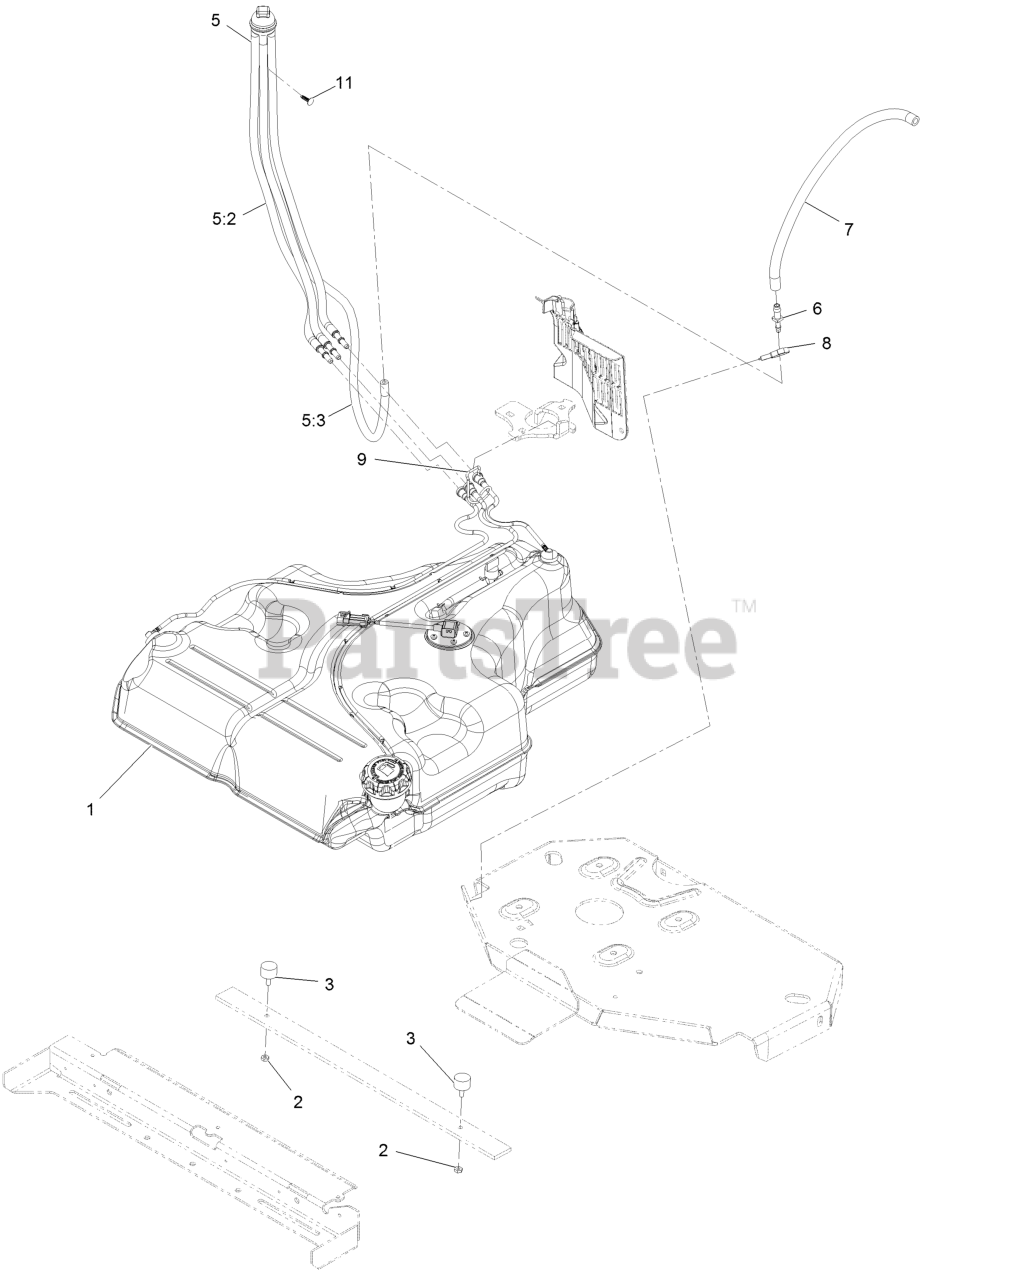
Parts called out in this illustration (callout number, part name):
1	Fuel Tank ASM
2	Nut-Jam 1/4-20
5	Fuel Manifold Vent ASM
5:2	Hose-Fuel Line 24"
5:3	Hose-Fuel
6	Fitting-Straight
7	Hose-Fuel
8	Clamp-Hose
9	Retainer-Line, Vapor
11	Plug-Plastic
